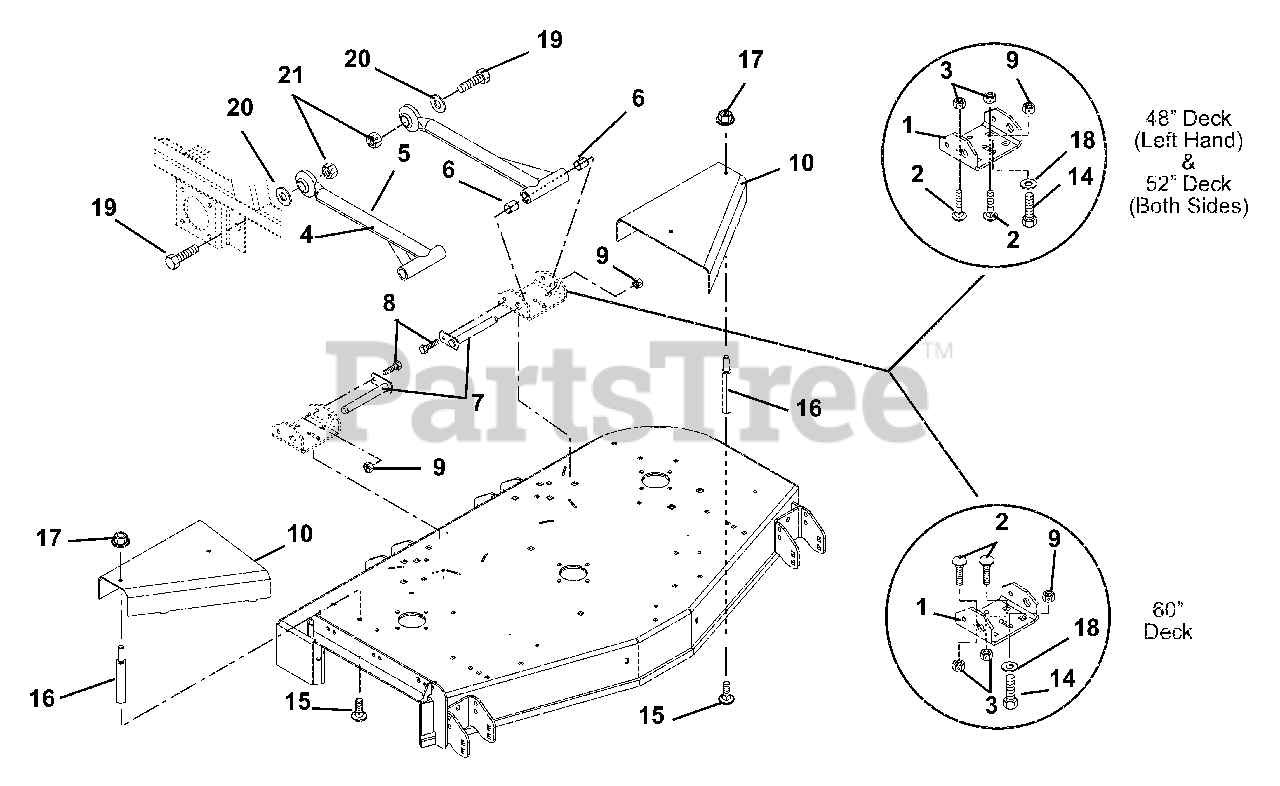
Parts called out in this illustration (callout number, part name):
1	BRKT, MOWER MOUNT - ORANGE
2	@BLT-RDHDSQNK .50-13X.75 G5YZ
3	NUT-LK-CTR-JAM .50-13 YWZC(ND)
4	ASSY, MOWER MOUNTING
5	MOWER MTG ARM - BLACK
6	BRG, .750 X .875 X 1.000
7	WELDMENT, MOWER MTG. PIN
8	@BLT-HEX .38-16X.75 GR5 YWZC
9	@NUT-LK-TOP-FLG .38-16 YWZC
10	GUARD, PULLEY LH - ORANGE
11	GUARD, PULLEY RH - ORANGE
12	GUARD, PULLEY LH - ORANGE
13	GUARD, PULLEY RH - ORANGE
14	@BLT-RDHDSQNK .38-16X.75 G5YZ
15	BLT,RDHDSQNK .31-18X.75 LOCTIT
16	STANDOFF, 2.75 X 5/16-18
17	@NUT-LK-TOP-FLG .31-18 YWZC
18	@WSHR-FL-STL.406X.812X.065 YWZ
19	BLT-HEX .875-9X2.75 GR5 YWZC
20	WSHR-FL-STL .890X1.500X.1196YZ
21	NUT-LK-CTR .875-9 YWZC
